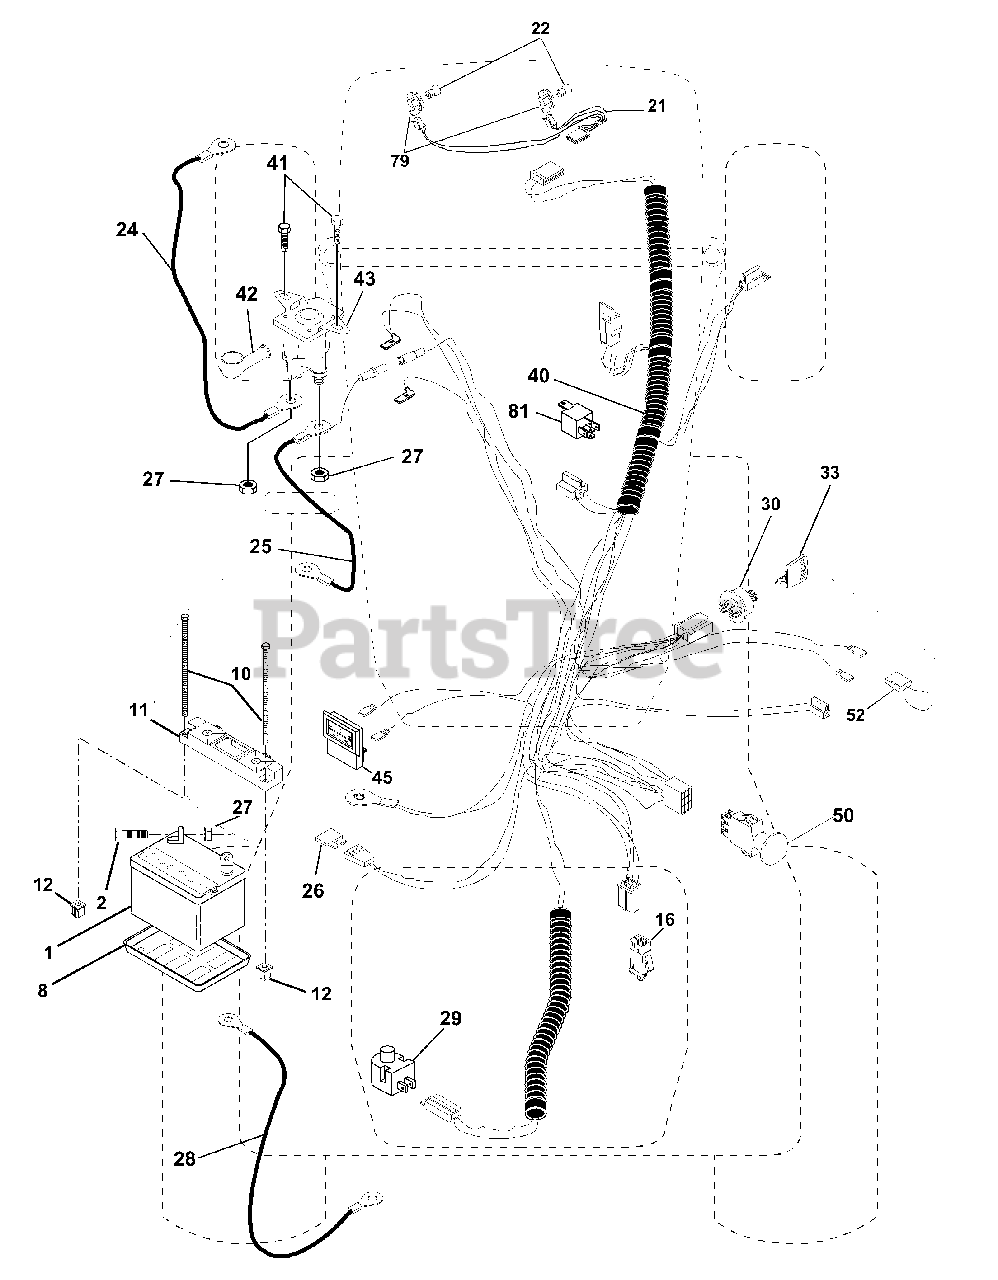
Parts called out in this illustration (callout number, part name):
1	Battery
2	Bolt Hex Head 1/4-20 x 3/4
8	Tray, Battery
10	Bolt Btr Frt 1/4-20 X 7.5 zinc
11	Holdown Battery Front Mount
12	Nut Push Nylon 1/4"
16	Switch Interlock Push-In
21	Harness Headlight
22	Bulb Light
24	Cable, Battery
25	Cable, Battery
26	Fuse
27	Nut Keps Hex 1/4-20 Unc
28	Cable,Ground
29	Switch, Plunger
30	Switch, Ign
33	Key
40	Harness, Ignition
41	Screw 1/4-20 x 1/2
42	Cover, Terminal Red
43	Solenoid
45	Ammeter
50	Switch, PTO
52	Protection Wire Loop
79	Bulbholder
81	Relay Asm.
